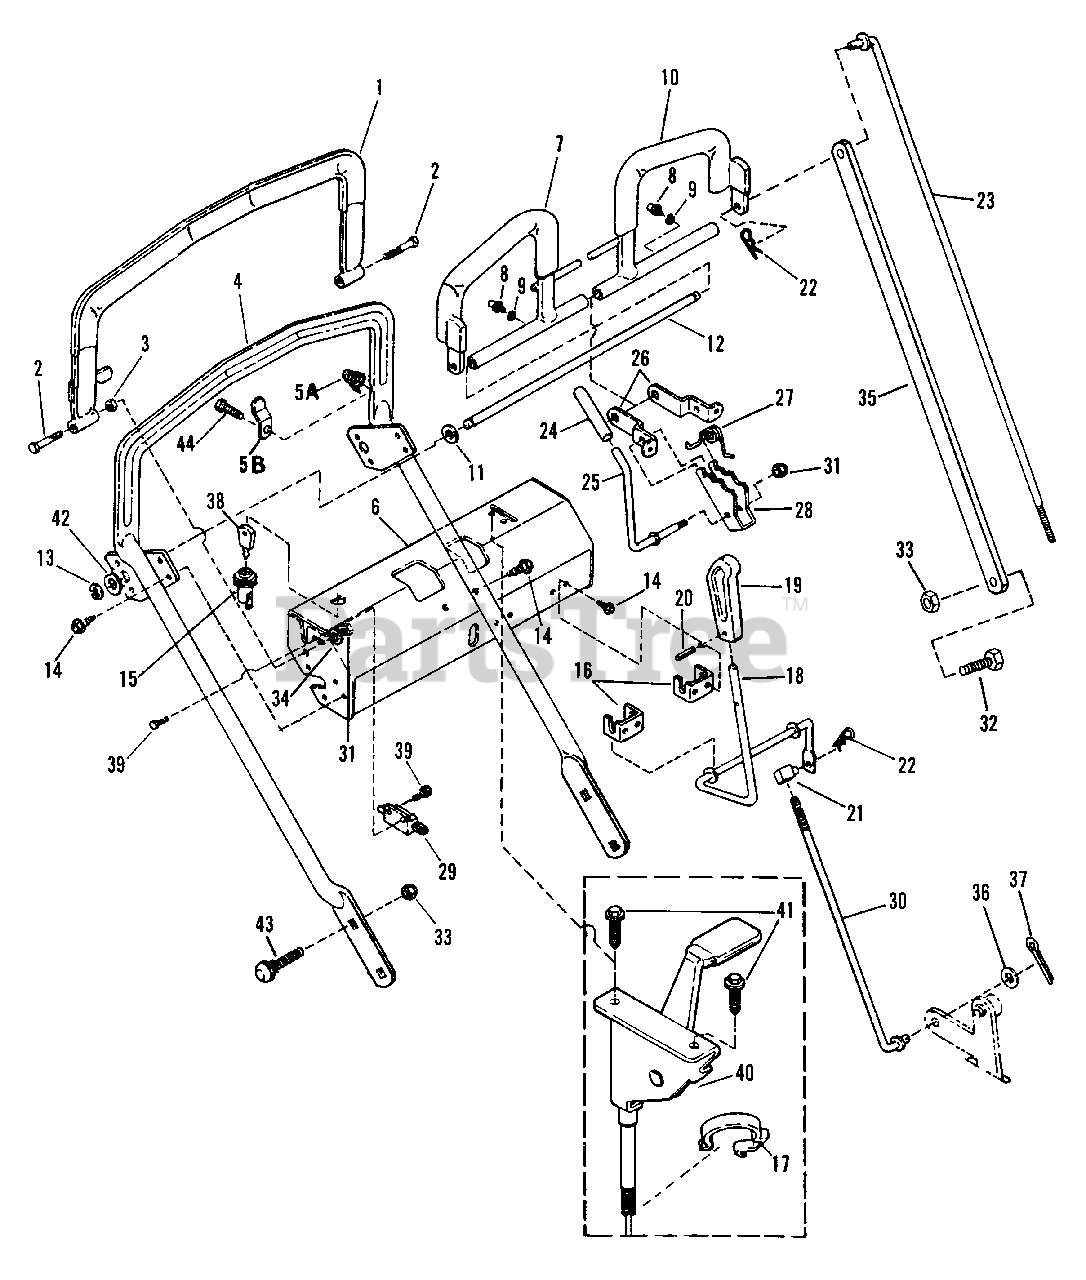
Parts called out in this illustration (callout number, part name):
1	BAIL, OPC (With Grip)
2	BOLT, 1/4-20 X 1-3/4" GD5 YZ
3	NUT, 1/4-20 Hex
4	HANDLE, Loop
5A	SPRING, Conical
5B	SPRING, Loop Handle
6	CONTROL, Console
7	LEVER, Traction (Right Hand)
8	FITTING, Lube
9	WASHER, 1/4 Internal Tooth Lock
10	LEVER, Traction (Left Hand)
11	WASHER, 1/2 Flat
12	ROD, Pivot
13	E-RING, 1/2
14	SCREW, 1/4-20 x 1/2" Self-Tapping
15	SWITCH, On-Off
16	BRACKET, Lever Mounting
17	CLIP, Cable
18	LEVER, Blade Engagement
19	KNOB
20	PIN, 3/16 x 3/4" Roll
21	SWIVEL
22	HAIR-PIN, 3/32 x 1 3/16"
23	ROD, Traction
24	GRIP, Neutral Latch
25	LEVER, Neutral Latch
26	BRACKET, Neutral Mounting
27	SPRING, Neutral
28	LATCH
29	SWITCH, OPC
30	ROD, Blade Clutch (Loop Handle)
31	NUT, 1/4-20 Hex, Nyloc
32	BOLT, 3/8-16 X 1" GD5 CZ
33	NUT, 3/8-16 HEX NYLON LOCK
34	WASHER, 1/4 Flat
35	STRAP, Brake Loop
36	WASHER, 3/8" USS
37	COTTER-PIN, 3/32 x 1"
38	KEY, Switch (With Cover)
39	SCREW, #12-14 x 1/2" Self-Tapping
40	CONTROL, Throttle
41	SCREW, #10-24 x 1/2" Hex Washer Self-Tap (Torx)
42	BUSHING, 1/2 Machine
43	BOLT, 3/8-16 x 1" Carriage
44	SCREW, 5/16-18 x 3/8" Self-Tapping
